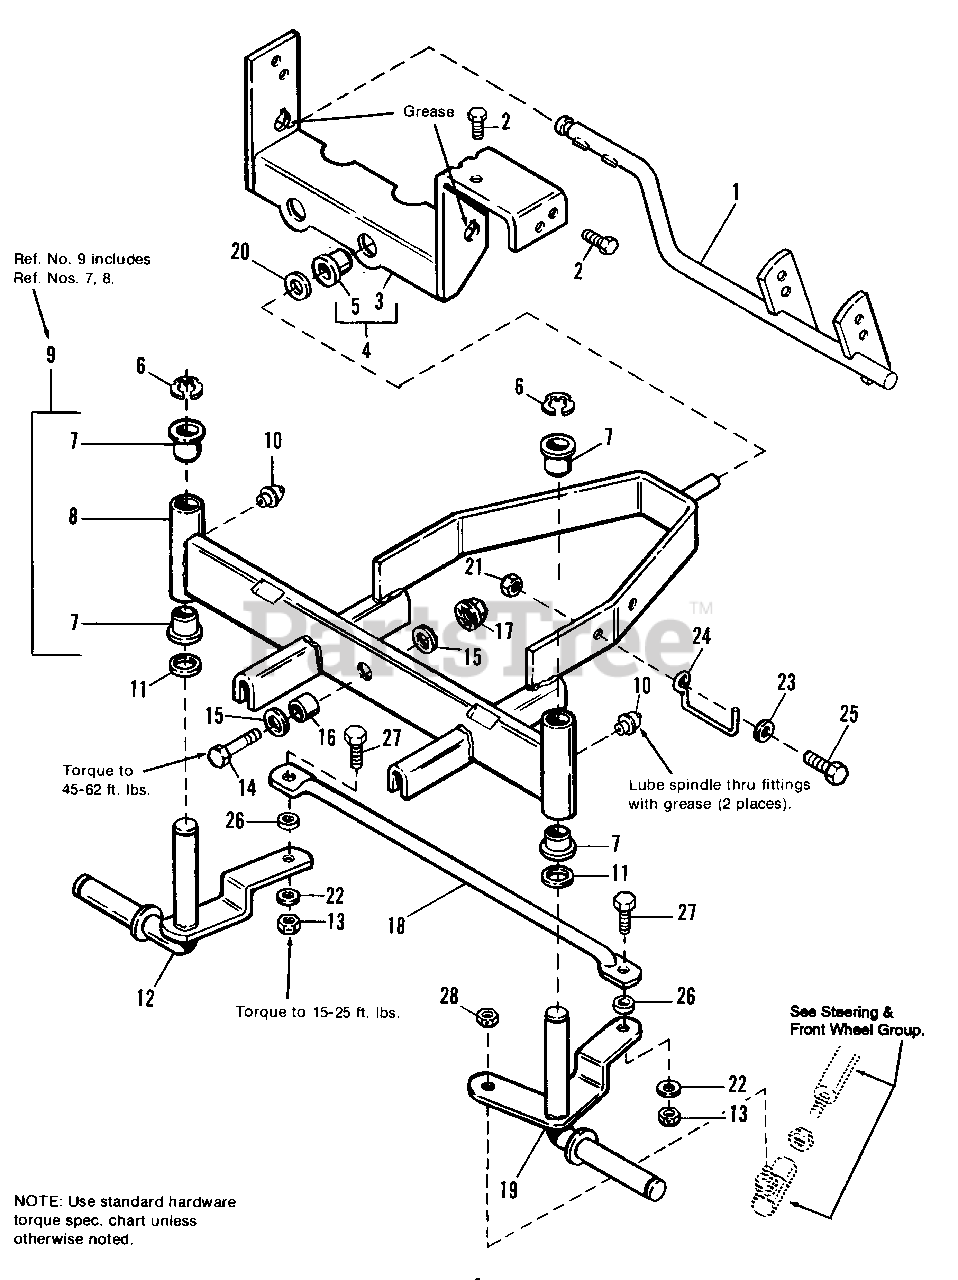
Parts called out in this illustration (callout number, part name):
1	LEVER ASSY., Brake
2	SCREW, Taptite, 5/16-18 x 3/4
4	SUPPORT ASSY., Rear (Incl. Ref. No. 5)
6	KLIPRING, Ext., 3/4
9	AXLE ASSY., Front (Incl. Ref. Nos. 7 & 8)
10	FITTING, Lube, Drive Type
11	WASHER
12	SPINDLE ASSY., R.H. (12 HP)
13	LOCKNUT, Hex, 3/8-16
14	CAPSCREW, Hex, 1/2-13 x 1-3/4 (Gr. 8)
15	WASHER
16	SPACER
17	LOCKNUT, Hex Flange Lock, 1/2-13
18	TIE ROD ASSY.
19	SPINDLE ASSY., L.H.
21	NUT, Hex, 5/16-18
22	WASHER, 3/8
24	GUIDE, Drag Link
25	CAPSCREW, Hex Hd., 5/16-18 x 1
27	CAPSCREW, 3/8-16 x 1
28	LOCKNUT, Center, 1/2-20
